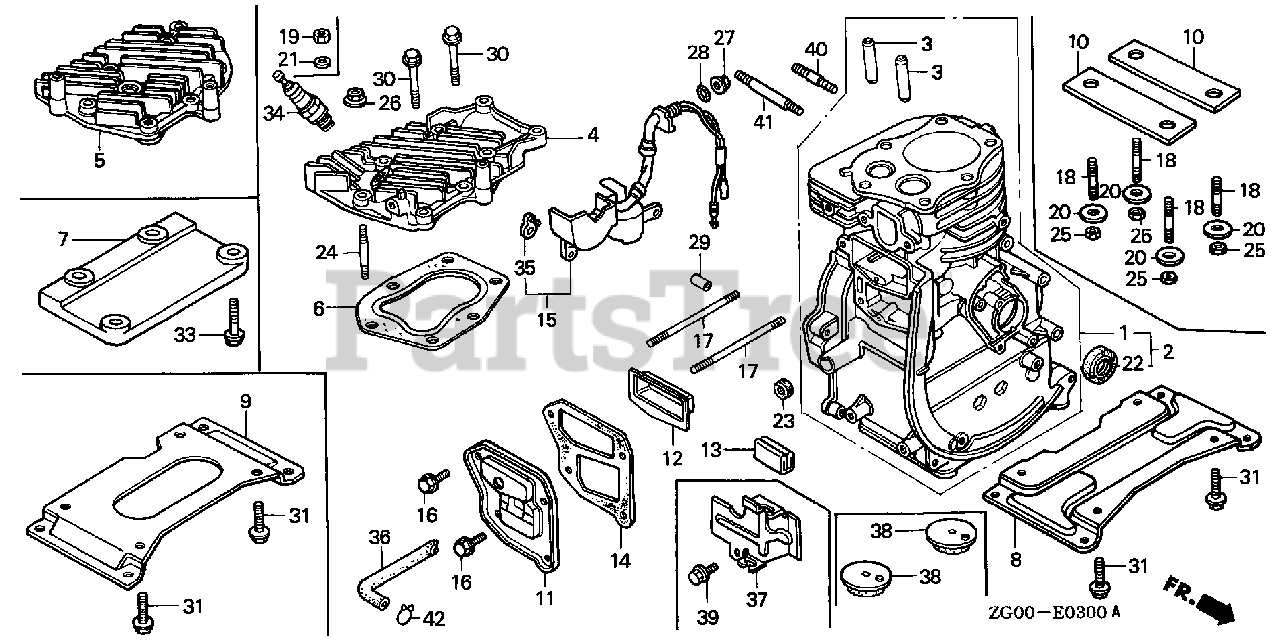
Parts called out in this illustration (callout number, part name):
3	GUIDE, VALVE (OS)
4	CYLINDER HEAD
6	GASKET, CYLINDER HEAD
8	BED, ENGINE (Q-TYPE)
9	BED, ENGINE (Q-TYPE)
11	COVER, TAPPET (NOT AVAILABLE)
12	SEPARATOR (INNER) (NOT AVAILABLE)
14	GASKET, TAPPET COVER
16	BOLT, FLANGE (5X10)
17	BOLT, STUD (5X80)
22	OIL SEAL (17X30X6) (NOK)
24	BOLT, STUD (6X45) (SOURCE: VINTAGE PARTS INC.)
26	NUT, FLANGE (6MM)
29	PIN A, DOWEL (8X14) (YAMADA)
30	BOLT, FLANGE (6X35)
31	BOLT, FLANGE (8X18)
34	SPARK PLUG (BM4A) (NGK)
34	SPARK PLUG (BMR4A) (NGK)
34	SPARK PLUG (W14M-U) (DENSO)
34	SPARK PLUG (W14MR-U) (DENSO)
34	SPARK PLUG (BPMR4A-10) (NGK)
34	SPARK PLUG (W14MP-U10) (DENSO)
